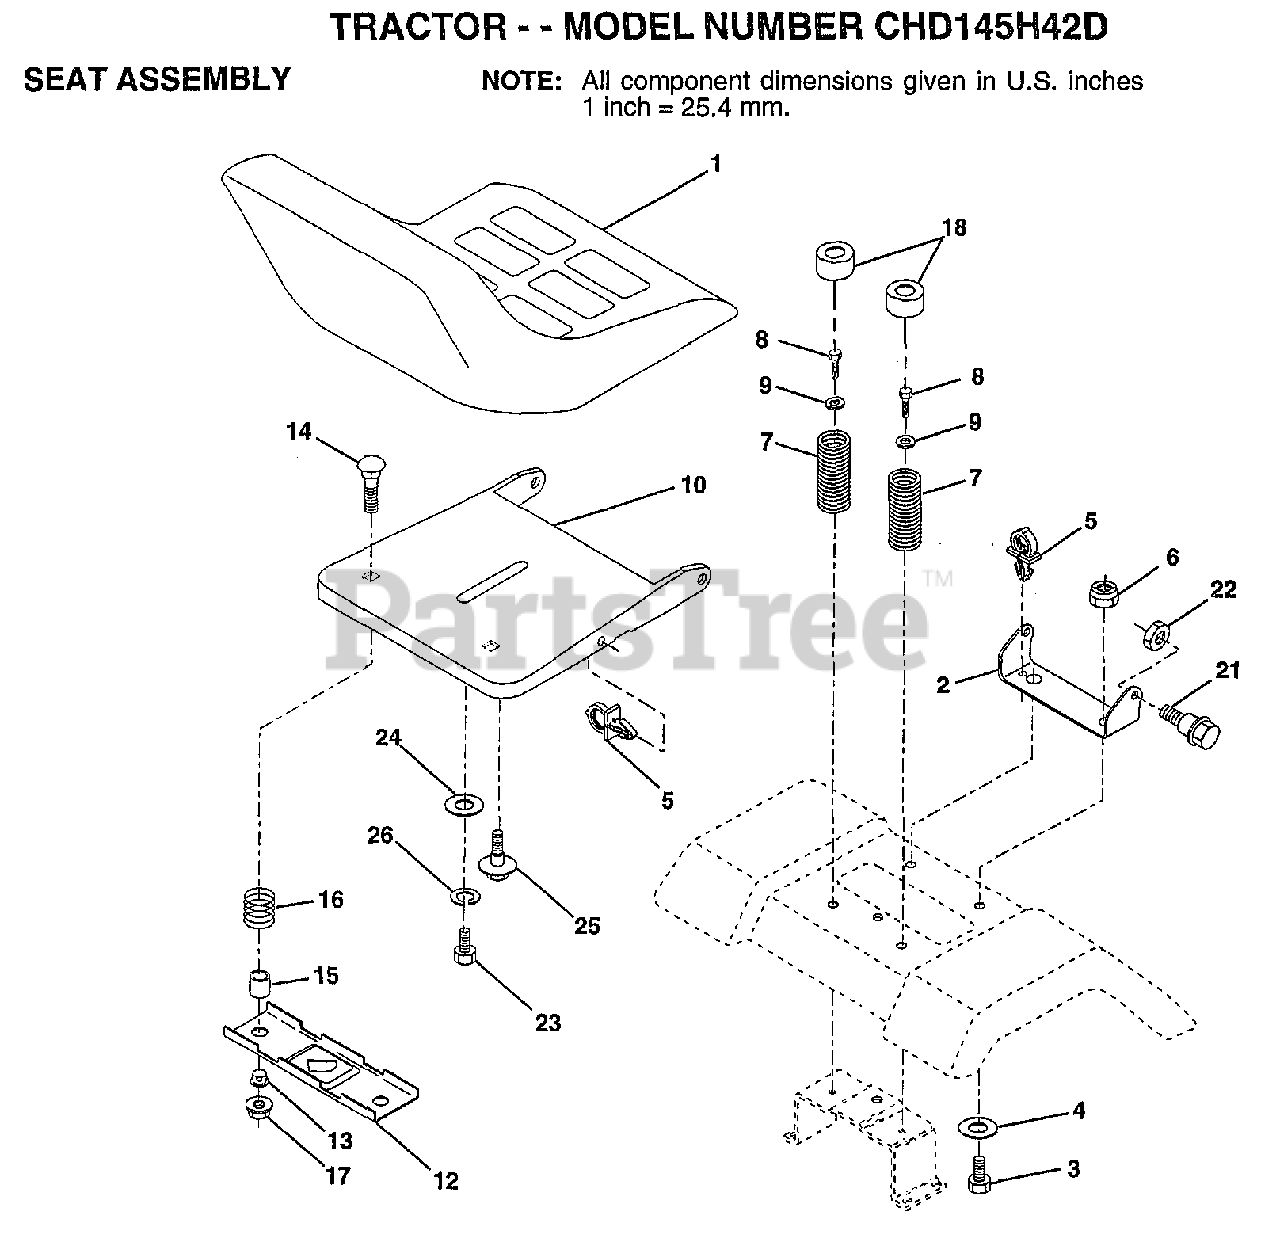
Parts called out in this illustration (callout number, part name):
1	SEAT
2	BRACKET PVT SEAT
3	BOLT
4	WASHER PM
5	CLIP.PUSH-IN.HING
6	NUT
7	SPRING COMPRESSIO
8	SCREW GTV
9	WASHER
10	PAN-SEAT
12	BRKT SWITCH
13	BUSHING
14	BOLT-RD HD SQ NK
15	SPLIT SPACER
16	SPRING
18	CAP SPRING
21	"BOLT,SHOULDER"
22	NUT
23	BOLT
24	WASHER
25	"BOLT,SHOULDER"
26	LOCKWASHER
